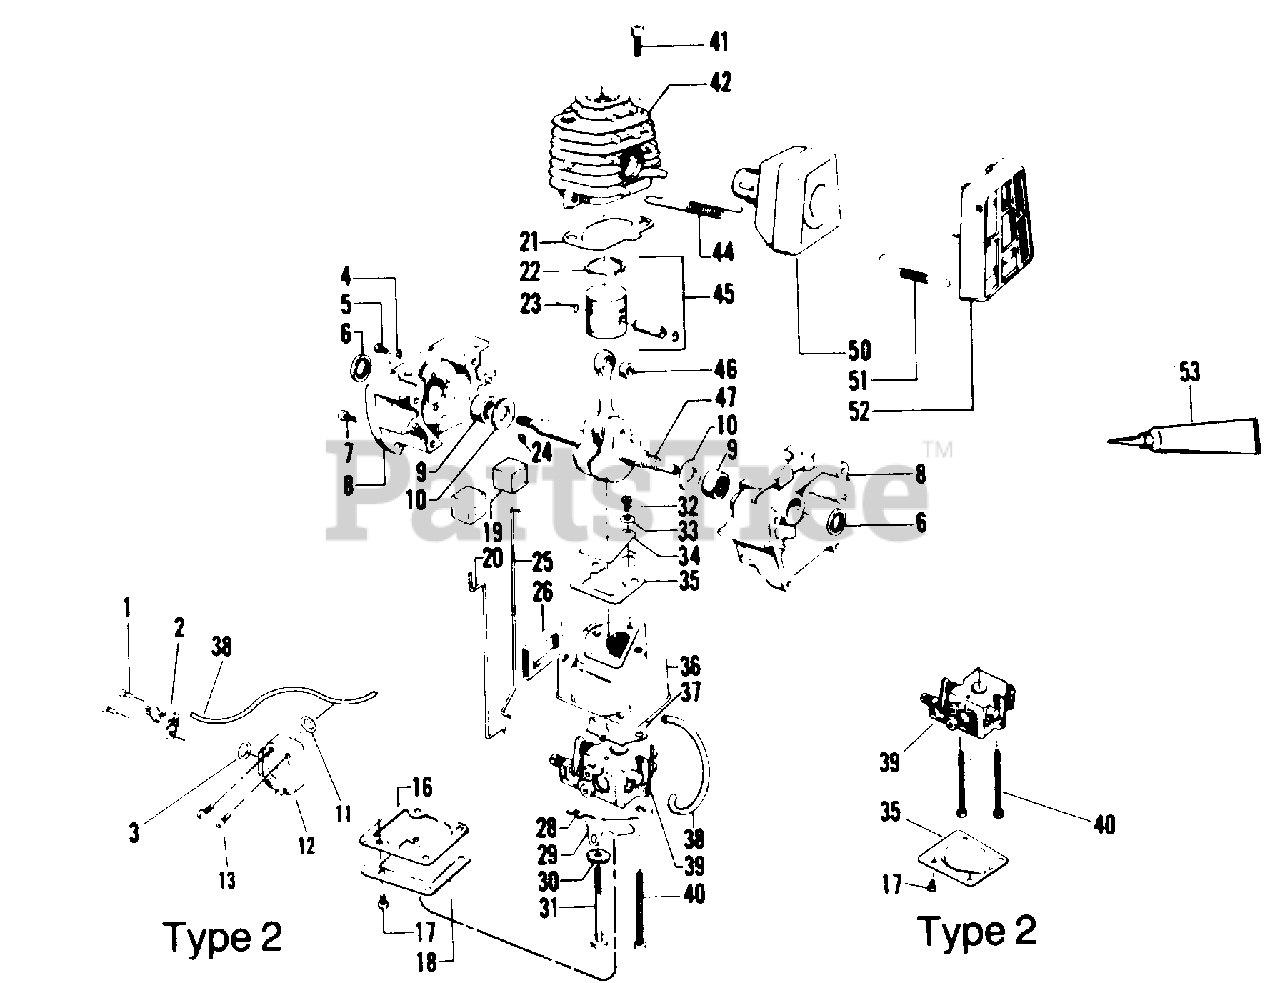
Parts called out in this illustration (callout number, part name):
1	Screw - Type 2 only
2	Accumulator Cap Ass'y. - Type 2 only (Incl. Cap, Screen & O-Ring)
3	O-Ring - Accumulator Chamber Type 2 only
4	Choke Wire - Clamp - Type 1 only
5	Choke Rod Clamp - Screw - #8 - 32 x 5/16" - Pan Hd. - Type 1 only
6	Crankcase - Seal
7	Screw - Crankcase #10 - 24 x 5/8" - Fil. Hd.
8	Crankcase Assembly (Incl. #6, 9 & Qty. 4 of #7)
9	Bearing - Crankshaft
10	Crankshaft Thrust - Washer
11	O-Ring (Orifice) - Type 2 only
12	Accumulator Ass'y. (Incl. #2, 3 & 11) Type 2 only
13	Screw - Type 2 only
16	Carburetor Case Cover - Gasket - Type 1 only
17	Carburetor Case Cover - Screw #8 - 18 x 9/16" - Pan Hd.
19	Throttle Choke Wire Boot
20	Choke Wire - See Service Ref. 4. - Type 1 only
21	Cylinder - Gasket
22	Piston Ring
23	Wrist Pin - Retainer
24	Flywheel - Key
25	Throttle Wire
26	Carburetor Case - Seal
29	Choke Shutter - Type 1 only
30	Wave Washer - #10 - Type 1 only
31	Carburetor Shoulder - Screw - Type 1 only #10 - 24 x 2-1/8" - Fil. Hd.
32	Reed Valve - Screw - #6 - 19 x 5/16"
33	Washer - #6
34	Reed Valve
35	Carburetor Case to Crankcase - Gasket
36	Carburetor Housing
37	Carburetor Gasket
38	Carburetor Fuel Line
39	Carburetor - See Service Ref. 2.
41	Cylinder - Screw - #1/4 - 20 x 3/4" - Socket Head
42	Cylinder
44	Muffler Attachment - Spring
45	Piston Kit
46	Wrist Pin Bearing
47	Crankshaft & Rod Assembly
51	Spring - Muffler Guard
52	Muffler - Guard
53	Crankcase - Sealant (Optional)
